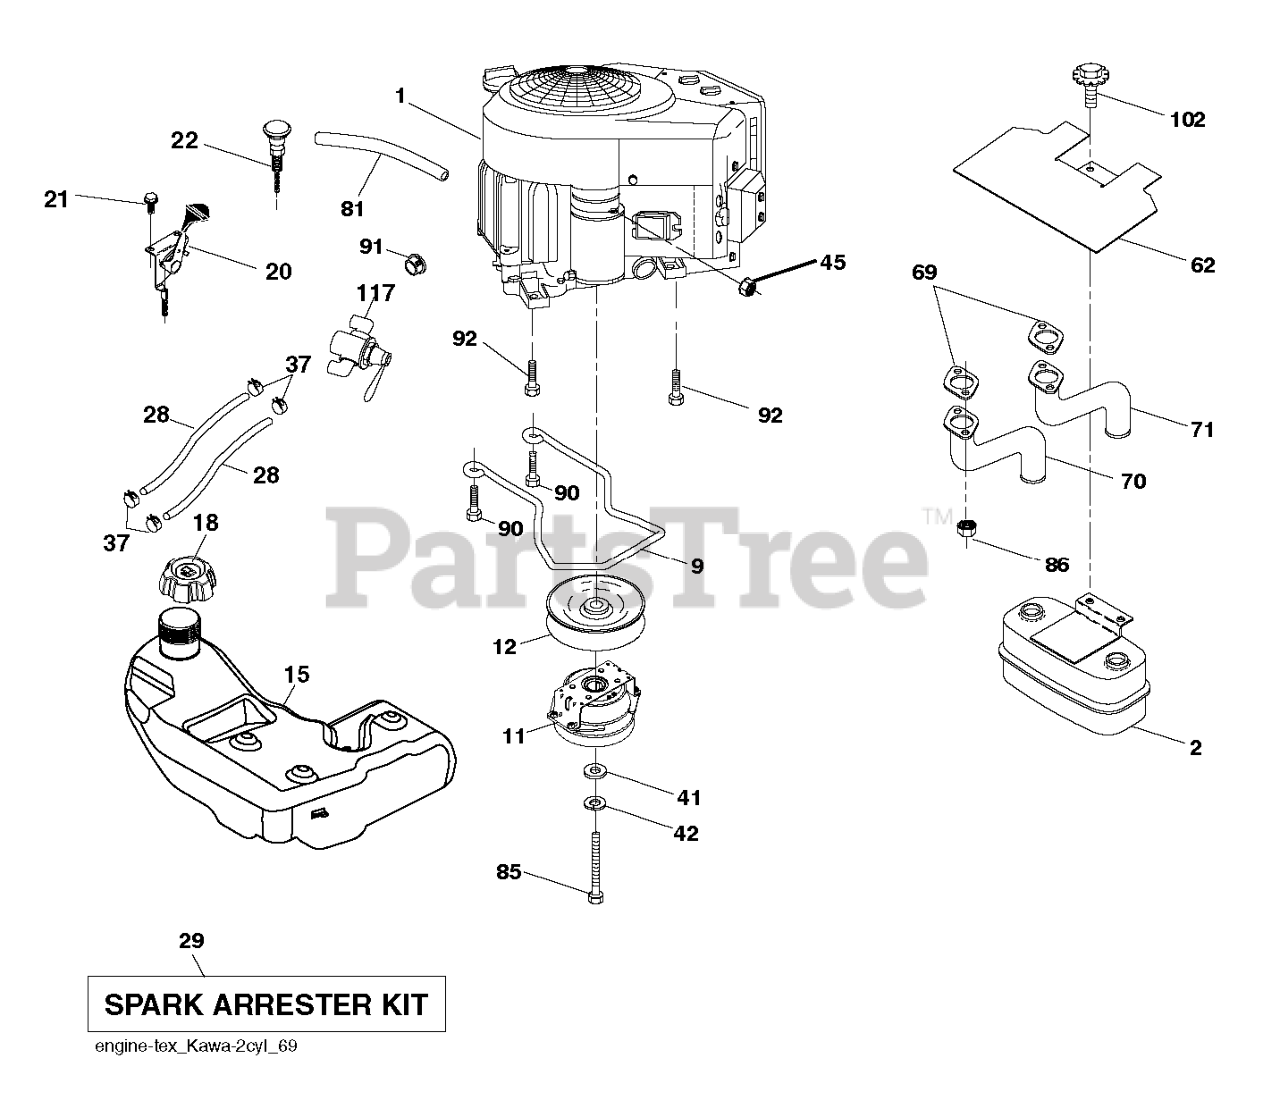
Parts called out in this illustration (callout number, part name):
2	MUFFLER.ASM.TWIN.MNTG.BRACKET
9	KEEPER.BELT.ENG.4.25"2.BLT.431
11	CLUTCH.OGURA.5.0PD.GT1.5A-EH01
12	PULLEY ENGINE
15	Tanks
18	FUEL CAP
18	CAP ASSY FUEL 3" GRAY
20	CONTROL.THROTTLE.COBRA.BLACK
21	SCREW.#10 X 0.750.BOS
22	CONTROL, CHOKE
28	LINE.FUEL.64"REAR.EMIS
29	KIT.SPARK ARRESTOR 794945 B&S
37	HOSE CLAMP
42	WASHER 7/16 LOCK
45	NUT
62	SHIELD.HEAT.MUFFLER
70	TUBE.EXHAUST.LH.FR961/FR730
71	TUBE.EXHAUST.RH.FR961/FR730
81	TUBE, DRAIN OIL ASM.
85	BOLT.HEX.7/16-20X3.GR5.YELLOW
86	NUT.HEX.FLANGE.TOPLOCK
90	SCREW 3/8-16X1
91	BUSHING.1.375OD
92	SCREW 3/8-16X1
102	SCREW
117	VALVE FUEL RESERVE
